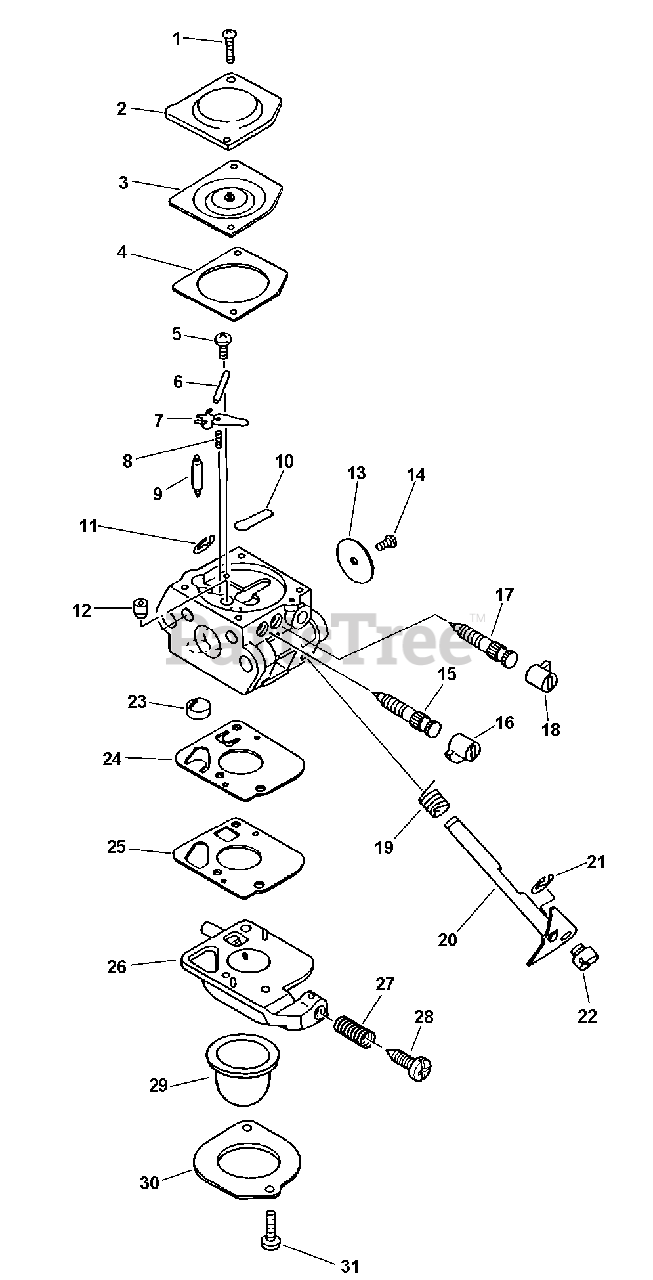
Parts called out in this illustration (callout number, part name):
2	Cover, Metering Chamber
3	Diaphragm, Metering
4	Gasket, Diaphragm Metering
5	Screw, Metering Pin
6	Pin, Metering Lever
7	Lever, Metering
8	Spring, Metering Lever
9	Valve, Needle
10	Plug, Welch
11	Clip, Throttle Shaft
12	Nozzle, Check Valve
13	Valve, Throttle
14	Screw, Throttle Valve
15	Needle, High Speed
16	Cap, limiter H.S.
17	Needle, Idle
18	Cap, limiter l.S.
19	Spring, Throttle Return
20	Shaft, Throttle
21	Clip, Swivel
23	Strainer
24	Diaphragm, Fuel Pump
25	Gasket, Fuel Pump
26	Base, Purge
27	Spring, Idle Adjuster
28	Screw, Idle Adjust
29	Pump, Purge
